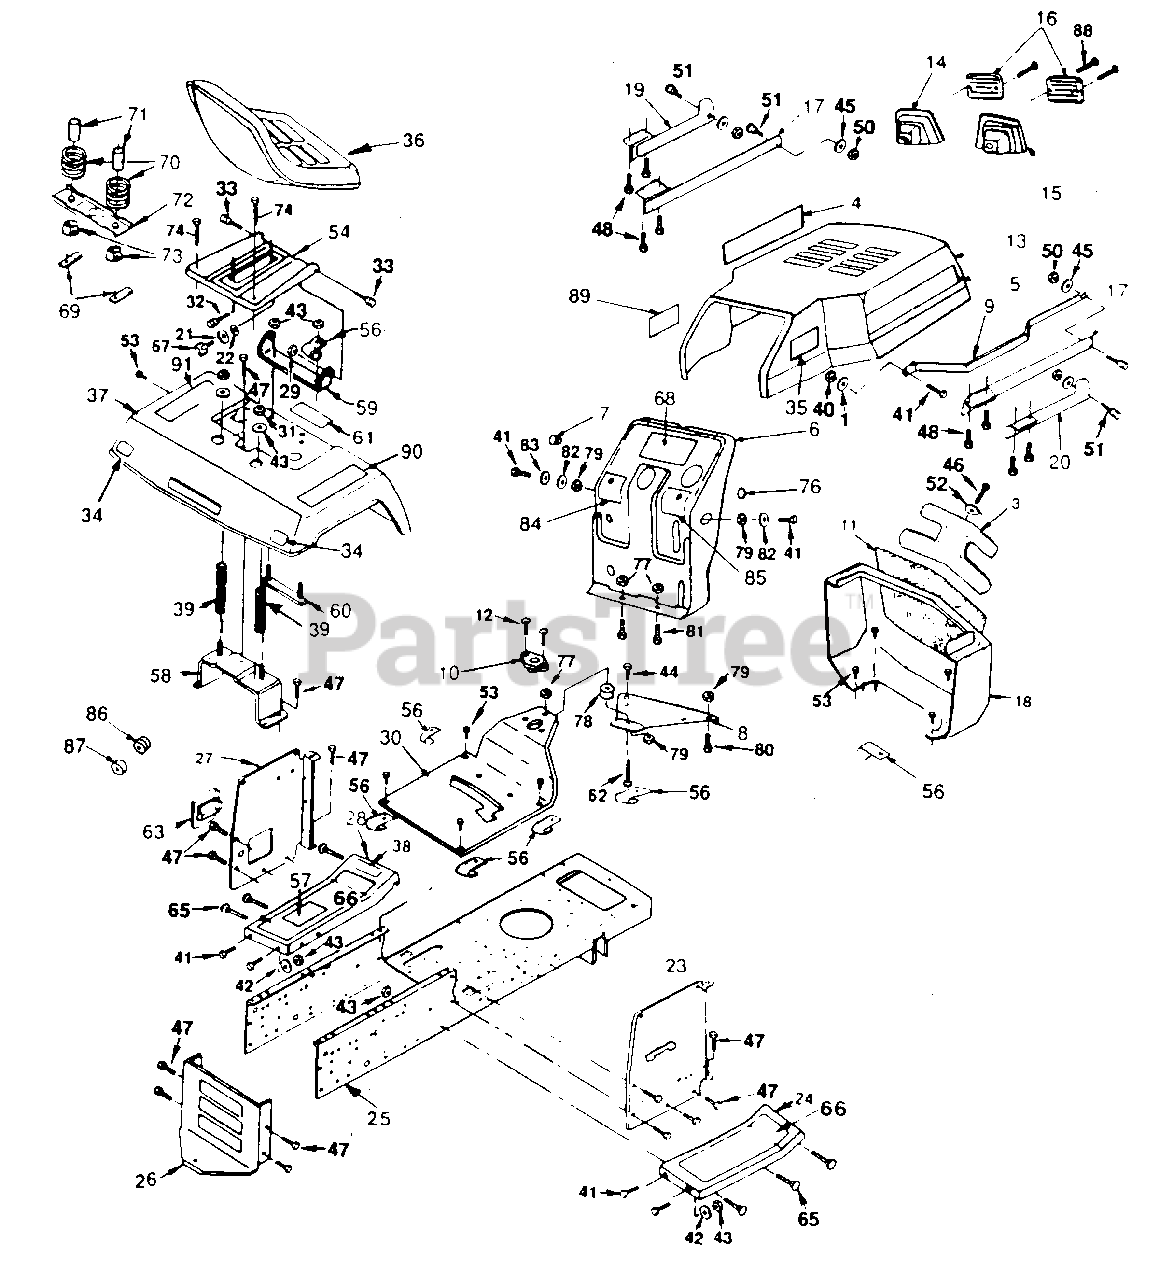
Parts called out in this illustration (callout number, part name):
1	Washer (AYP part number)
2	Decal (AYP part number)
3	Grill Insert
4	L.H. Poulan Hood Decal (AYP part number)
5	R.H. Poulan Hood Decal (AYP part number)
6	Dash (AYP part number)
7	Dash Plug (AYP part number)
8	Battery Support Plate (AYP part number)
9	Grill Brace (AYP part number)
10	Steering Bushing (AYP part number)
11	Grill Screen (AYP part number)
12	Hex Screw (AYP part number)
13	Hood (AYP part number)
14	L.H. Bezel (AYP part number)
15	R.H. Bezel (AYP part number)
16	Lens (AYP part number)
17	Rear Hinge Strap Assembly (AYP part number)
18	Grill Assembly
19	L.H. Hinge Strap Assembly (AYP part number)
20	R.H. Hinge Strap Assembly (AYP part number)
21	Washer (AYP part number)
22	Lock Washer 1/2 (AYP part number)
23	R.H. Dash Panel (AYP part number)
24	R.H. Footrest (AYP part number)
25	Chassis (AYP part number)
26	Drawbar (AYP part number)
27	L.H. Dash Panel (AYP part number)
28	L.H. Footrest (AYP part number)
29	Locknut
30	Saddle (AYP part number)
31	Washer (AYP part number)
32	Shoulder Bolt (AYP part number)
33	Shoulder Bolt (AYP part number)
34	Reflector (AYP part number)
35	R.H. HP Decal (AYP part number)
36	Seat (AYP part number)
37	Fender (AYP part number)
38	Clutch/Brake Decal (AYP part number)
39	Seat Spring (AYP part number)
40	Crownlock Nut 3/8-16
41	Hex Bolt 3/8-16 x 3/4 (AYP part number)
42	Washer (AYP part number)
43	Locknut
44	Hex Bolt 3/8-16 (AYP part number)
45	Washer (AYP part number)
46	Slotted Hex Screw (AYP part number)
47	Washer Hd. Hex Screw (AYP part number)
48	Special Washer Hd. Hex Screw (AYP part number)
49	Shoulder Bolt (AYP part number)
50	Locknut (AYP part number)
51	Shoulder Bolt (AYP part number)
52	Washer (AYP part number)
53	Washer Hd. Hex Screw (AYP part number)
54	Seat Pan (AYP part number)
56	Clip (AYP part number)
57	Ground Drive V-Belt Decal (AYP part number)
58	Fender Bracket Assembly (AYP part number)
59	Pivot Seat Bracket (AYP part number)
60	Fender Strap Assembly (AYP part number)
61	Caution Decal (AYP part number)
62	Hex Bolt (AYP part number)
63	Access Cover (AYP part number)
65	Carriage Bolt 3/8-16 x 3/4 (AYP part number)
66	Footrest Pad (AYP part number)
67	Seat Knob (AYP part number)
68	Dash Decal (AYP part number)
69	Foam Strip (AYP part number)
70	Spring (AYP part number)
71	Spacer (AYP part number)
72	Switch Bracket (AYP part number)
73	Snap Bushing (AYP part number)
74	Carriage Bolt (AYP part number)
75	Flange Locknut (AYP part number)
76	Dash Plug (AYP part number)
77	Keps Nut (AYP part number)
78	Spacer (AYP part number)
79	Keps Nut (AYP part number)
80	Hex Bolt (AYP part number)
81	Machine Screw (AYP part number)
82	Washer (AYP part number)
83	Ext. Tooth Lock Washer (AYP part number)
84	Clutch Attachment Decal (AYP part number)
85	Lift Attachment Decal (AYP part number)
86	Split Grommet (AYP part number)
87	Grommet (AYP part number)
88	Pan Head Screw (AYP part number)
89	L.H. HP Decal (AYP part number)
90	R.H. Fender Decal (AYP part number)
91	L.H. Fender Decal (AYP part number)
92	Hex Screw (AYP part number)
